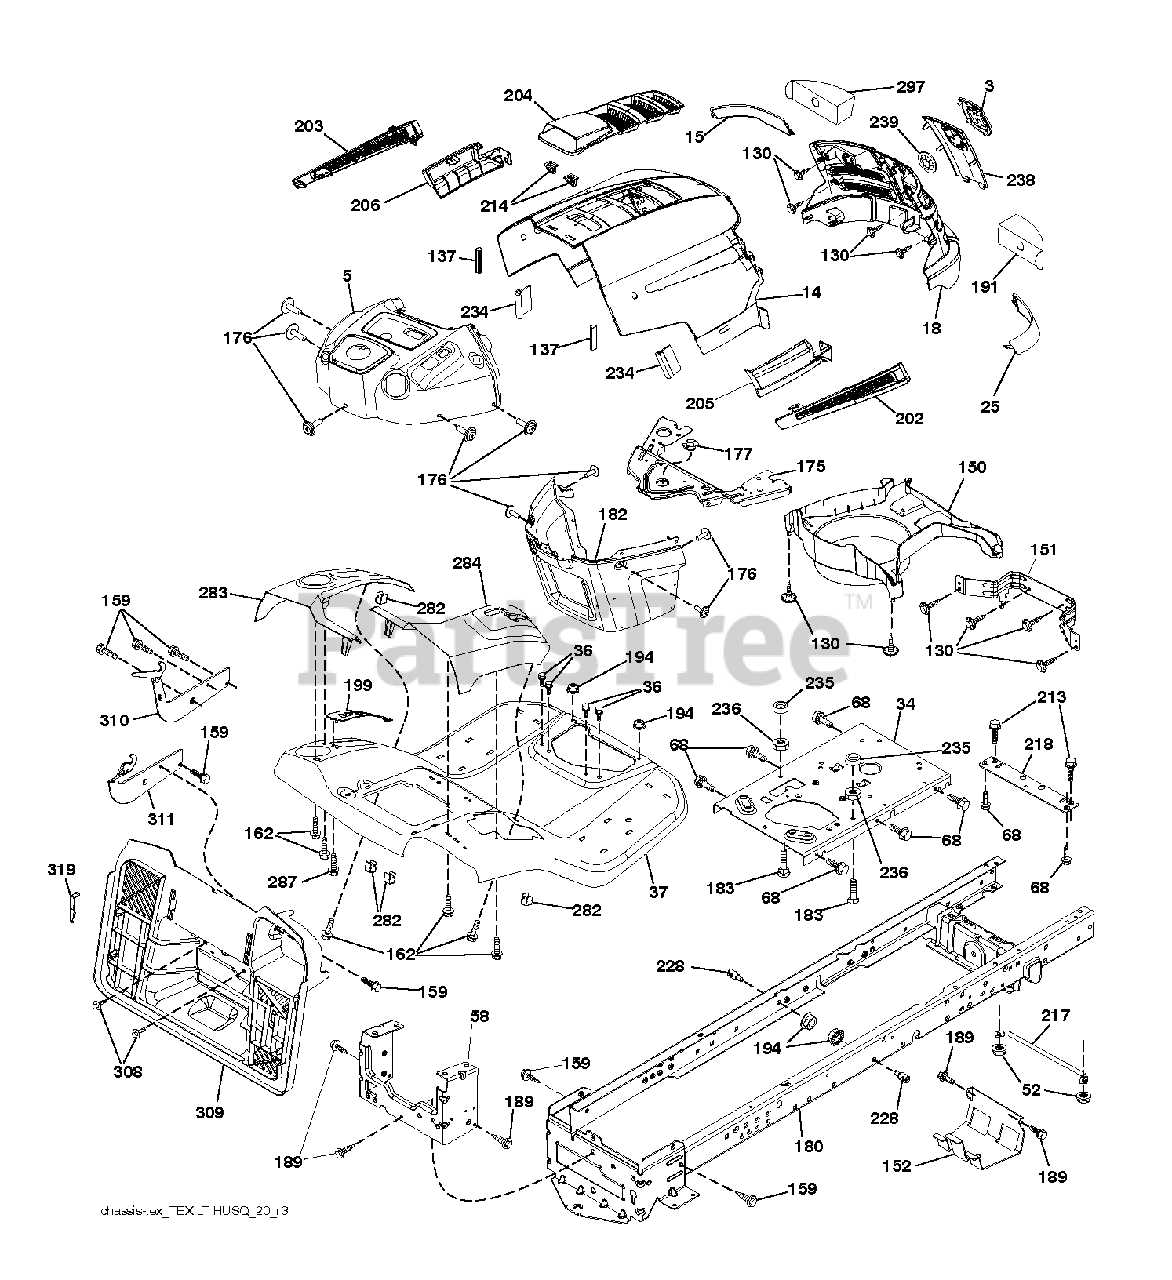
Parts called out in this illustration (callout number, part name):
3	RP LOGO
5	SUBASM.DASH.UPPER.HLT.498
14	HOOD.HUSQVARNA.LT.ORANGE
15	LENS.HUSQVARNA LT.RH
18	GRILLE.SVC.HUSQVARNA.GREY
25	LENS.HUSQVARNA LT.RH
34	PLATE.ENGINE.WELDED.CHASSIS
36	SCREW 5/16"
37	FENDER.TEX.SRD.CRD.BASE
52	LOCKNUT
58	DRAWBAR UPPER 2PC SMALL FENDER
68	SCREW LT
130	SCREW.#10 X 0.750.BOS
137	BUMPER DASH
151	BRACKET PIVOT
152	SHIELD.BROWNING.W/TEX
159	SCREW, 3/8-16X3/4
162	SCREW.HI-LO.CONSOLE
175	CROSSMEMBER
176	SCREW.#10-24X5/8.RN.QU
177	BUSHING STEERING
180	CHASSIS.WLDMNT.14GA.2PC.18".TI
182	DASH.LOWER.PREDATOR LT
183	BOLT.5/16-18X1-1/4 FULL THD
189	SCREW
191	INSERT.REFLECTIVE.RH.
194	NUT LOCK HEX FLANGE 5/16-18
199	PLATE DECK LIFT
202	VENT.SIDE.HUSQVARNA.LT.RT
203	VENT.SIDE.HUSQVARNA.LT.LFT
204	SUBASM.TOP.VENT.HUSQ.LT
205	SKIRT.SIDE.HUSQVARNA.LT.RT
206	SKIRT.SIDE.HUSQVARNA.LT.LEFT
213	BOLT
214	CLIP.RETAINER.TINNER.
217	ROD.PIVOT.HOOD
218	X-PIECE.HOOD.STOP.NON/
228	STUD.FASTNER.W/ANTI-ROTATE
234	BUMPER.HOOD.TEX.HUSQVARNA
235	SPACER FENDER
236	NUT.CENTERLOCK.5/16-
238	TRIM.HUSQ LT.668
282	CLIP.RETAINER.CONSOLE.LT.HUSQ
283	CONSL.DECKLIFT.LH.SRD.TEX.CRD
284	CONSL.SHFT.PEDAL.RH.SRD.TEXCRD
287	SCREW 1/4X20
297	INSERT REFLECTIVE
308	BOLT, 5/16-18 X 1 3/4
309	BACKPLATE.BAGGER.V2.SRD
319	BRACKET.ACTUATOR.BAGGER.SRD
